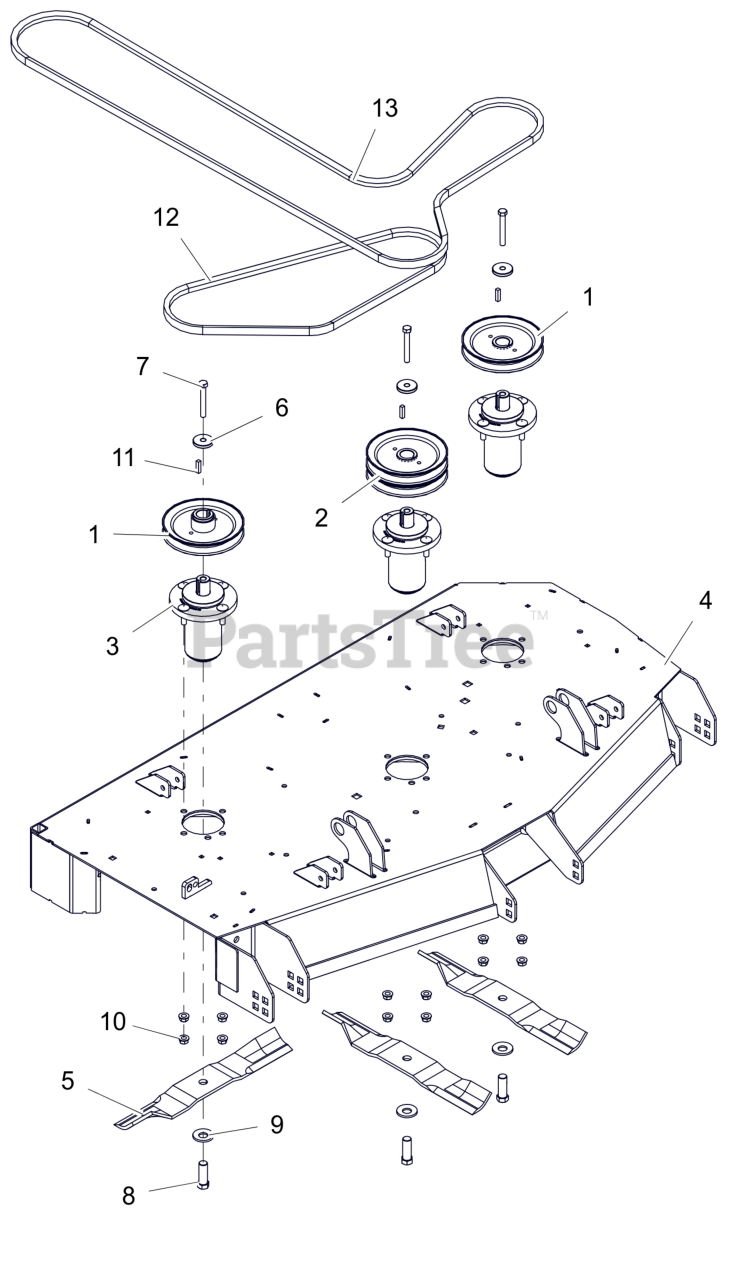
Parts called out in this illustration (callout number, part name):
1	PULLEY, SINGLE -1.000 ID X 6.000 OD
2	PULLEY, DOUBLE 1.000 ID X 6.000 OD
3	ASM, MAINT FREE ALUM SPINDLE
4	KIT, DECK - 48 W/DECALS - XF3
5	BLADE, 16.19" MOWER (HI-LIFT)
6	RETAINER, SHEAVE
7	BLT, HEX .38-16X2.75 G8 ZCC
8	BLT, HEX .62-18X1.75 G8 ZCC
9	WSHR-BLVL .669X1.535X.138
10	NUT-LK-CTR-FLG .375-16 GF ZCC
11	KEY, SQ .25X.25X1.00 RC 40-50
12	V-BELT, B-COGGED
13	V-BELT, HB SECTION
